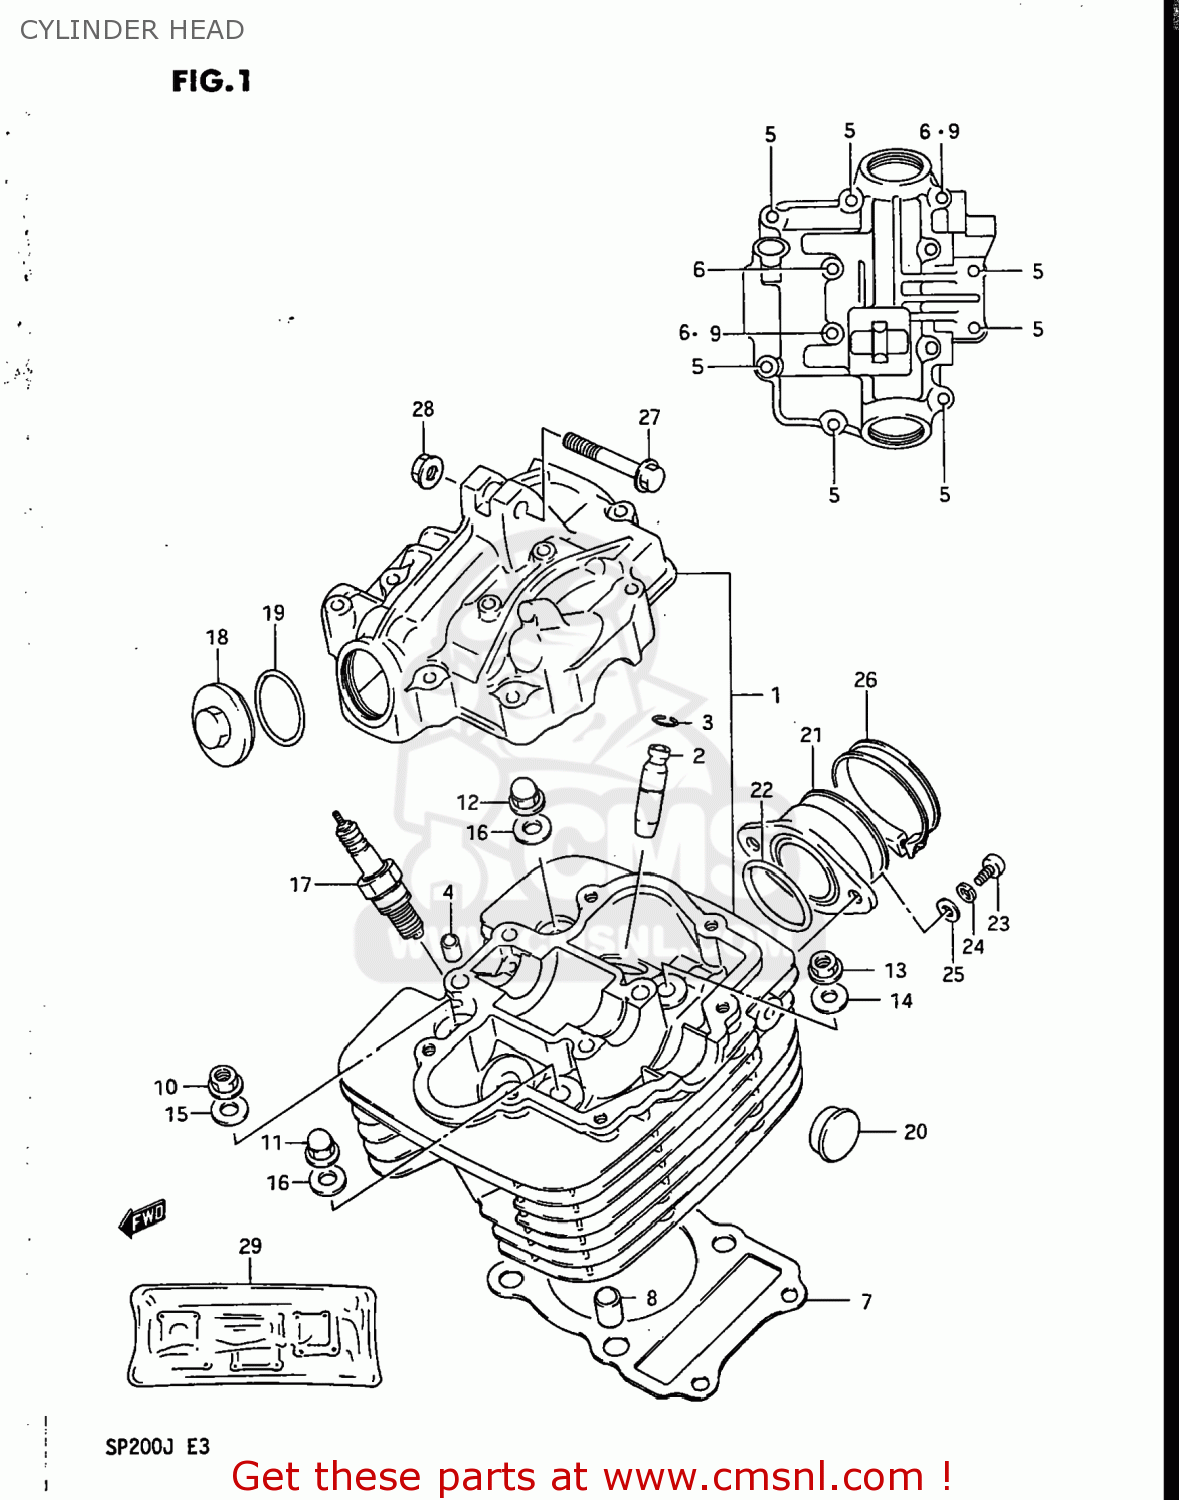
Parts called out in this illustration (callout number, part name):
1	HEAD ASSEMBLY,CYLINDER
2	GUIDE,VALVE
3	RING,SNAP
4	PIN(6.2X8X11)
5	BOLT 6X35
6	BOLT ,6X60
7	GASKET,CYLINDER HEAD (NAS)
8	PIN
9	GASKET(5.8X13X1.2) (NAS)
10	NUT 8MM
11	NUT (8MM)
12	NUT
13	NUT
14	WASHER (8.5X19X2.3)
15	WASHER(8.5X19X2.3)
16	GASKET (NAS)
17	SPARK PLUG D8EA
18	CAP,INSPECTION
19	O RING(D:3,ID:29.5)
20	PLUG(OD:22.5)
21	PIPE,INTAKE
22	O-RING,INTAKE PIPE
23	SCREW
24	WASHER,LOCK
25	WASHER
26	CLAMP
27	BOLT 8X50
28	NUT
29	GASKET SET
